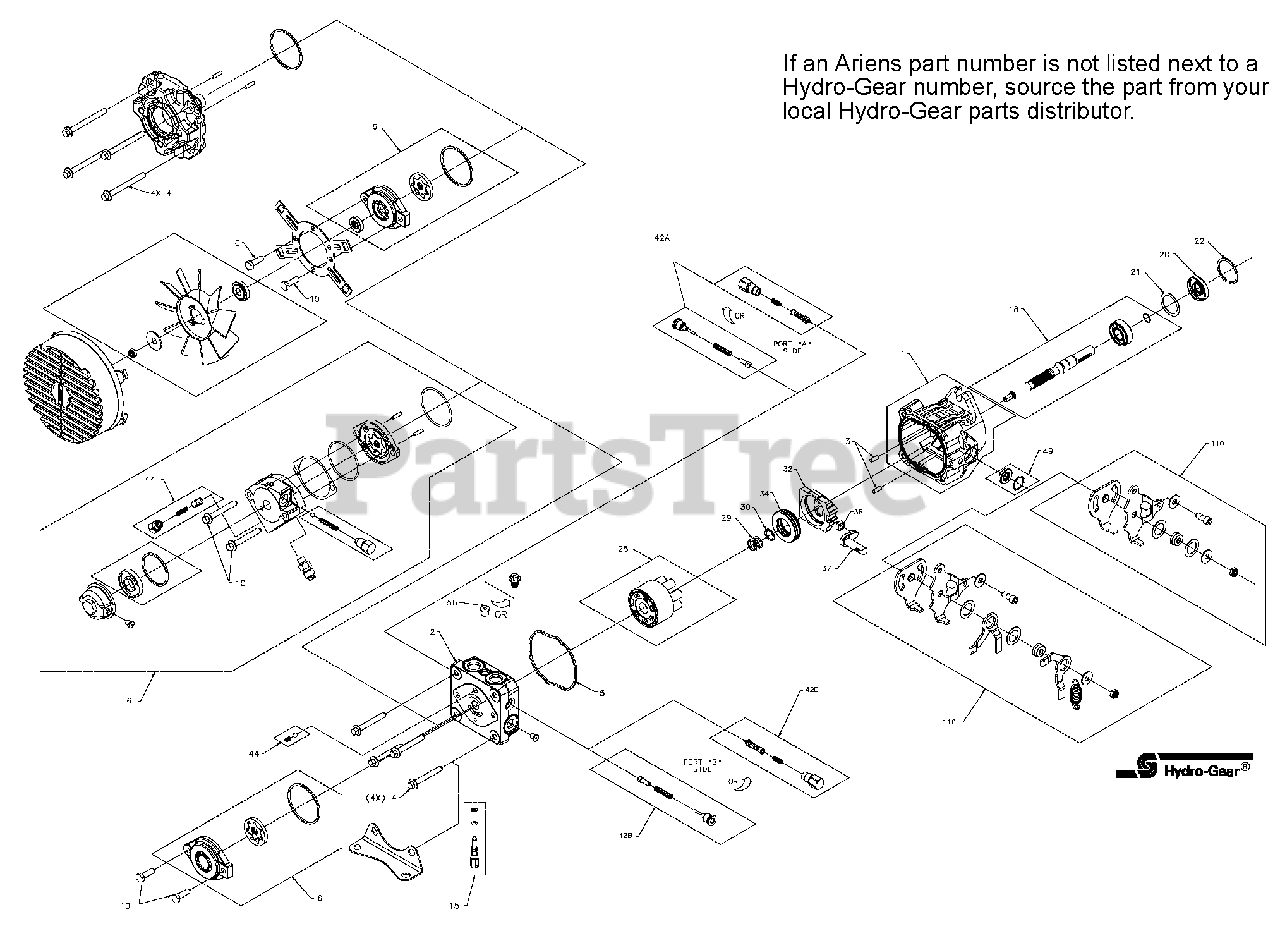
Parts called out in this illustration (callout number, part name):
1	KIT, HSG
2	ENDCAP
3	PIN, .219X1
4	HFHCS M8X60
5	O-RING, HSG
6	KIT, CHARGE PUMP
10	HHCS 5/16-18X1
15	KIT, BYPASS VALVE
18	KIT, PUMP SHAFT
20	SEAL, LIP 17X40X7
21	WASHER 1.23X1.56X.04
22	RING, RET 1.56 INT
25	Kit, Cylinder Block
29	SPRING. BLOCK
30	WASHER. THRUST .59 X .79 X .04
32	SWASHPLATE. VARIABLE
34	BEARING. THRUST 30 X 52 X 13
37	ARM. TRUNNION TAPERED SQUARE
38	GUIDE. SLOT
42	KIT, SHOCK VALVE 200 BAR
44	KIT, CHARGE RELIEF
49	BEARING, SHAFT BALL
56	PLUG 7/16-20 (METAL)
110	RETURN KIT
NS	KIT, PUMP SEAL
NS	KIT, AUX FILTER
